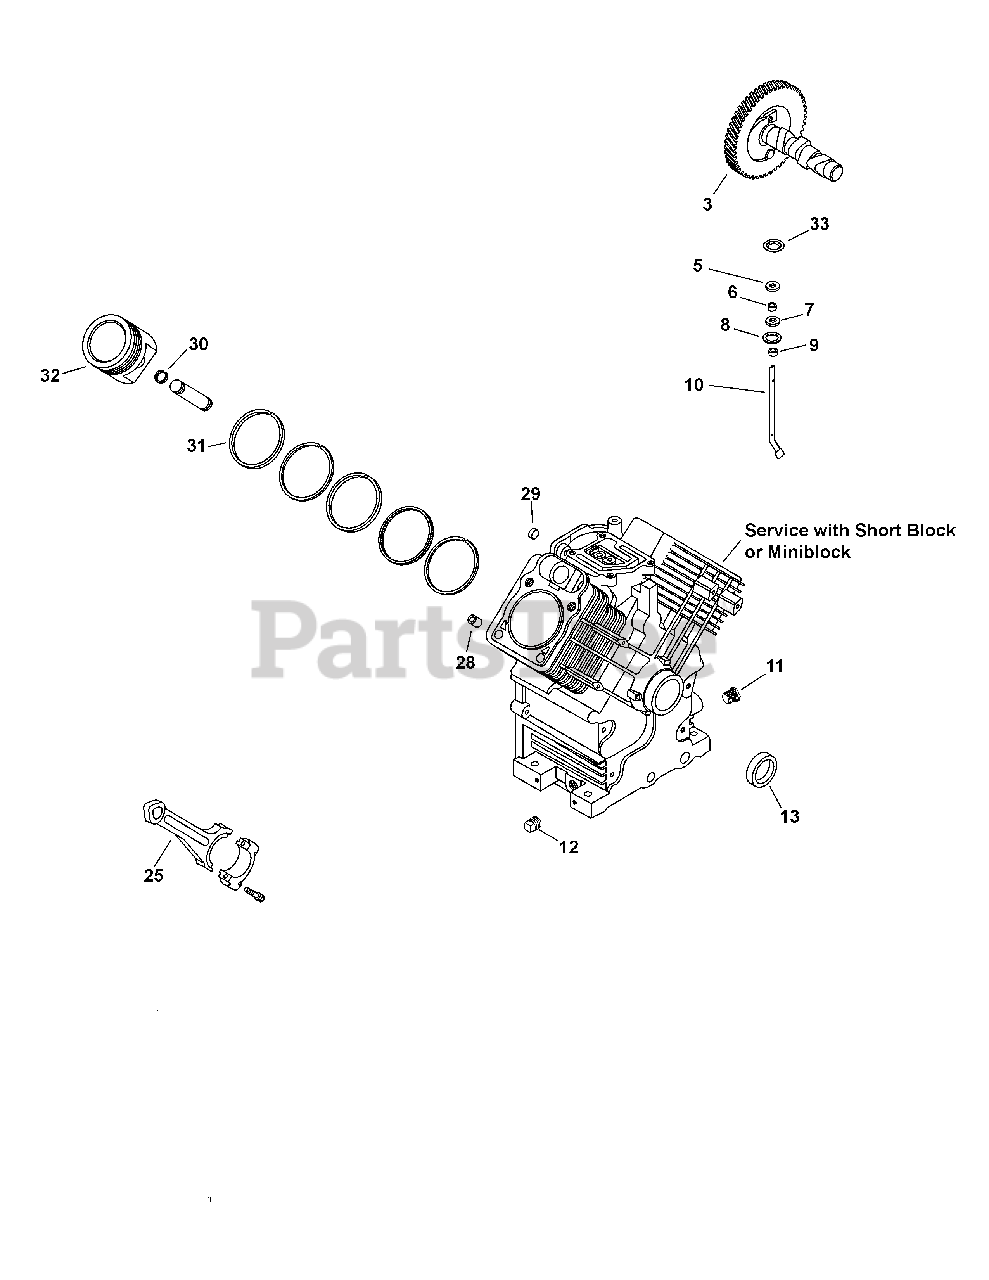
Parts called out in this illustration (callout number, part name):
3	Kit, Camshaft
5	Washer, Flat 9 Mm
6	Rod Assy, Connecting
7	Seal, Governor Cross Shaft
8	Washer, Flat 11/32"
10	Shaft, Governor Cross
12	Plug, Sq Hd Pipe 3/8"
13	Oil Seal (Helix Lip)
25	Kit, Connecting Rod
25	Kit, Connecting Rod Bolts
28	Pin, Locating
30	Retainer, Piston Pin
31	Ring Set (Std)
31	Ring Set (.08)
31	Ring Set (.25)
31	Ring Set (.50)
32	Kit,Piston Assy W/Ring(Std)77Mm
32	Kit,Piston Assy W/Ring Set(.08)77Mm
32	Kit,Piston Assy W/Ring Set(.25)77Mm
32	Kit,Piston Assy W/Ring Set(.5)77Mm
33	Retainer, Ring
